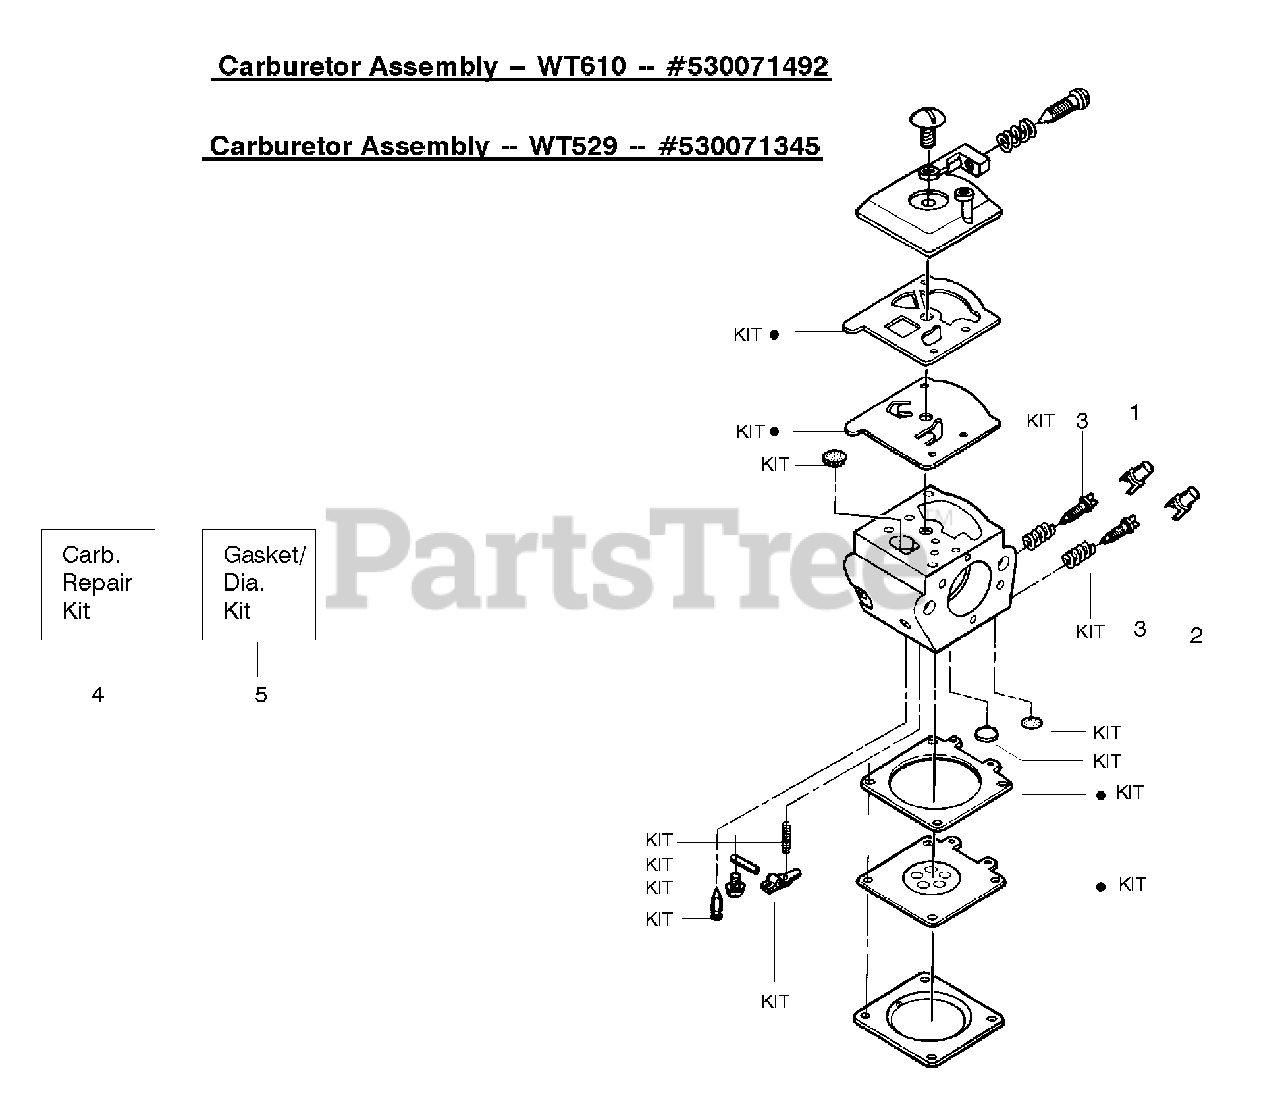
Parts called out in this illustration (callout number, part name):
1	Limiter Cap-High
2	Limiter Cap-Low
3	Needle-high/low speed
4	Kit-Carburetor Repair
5	Kit-Gasket Diaphragm
